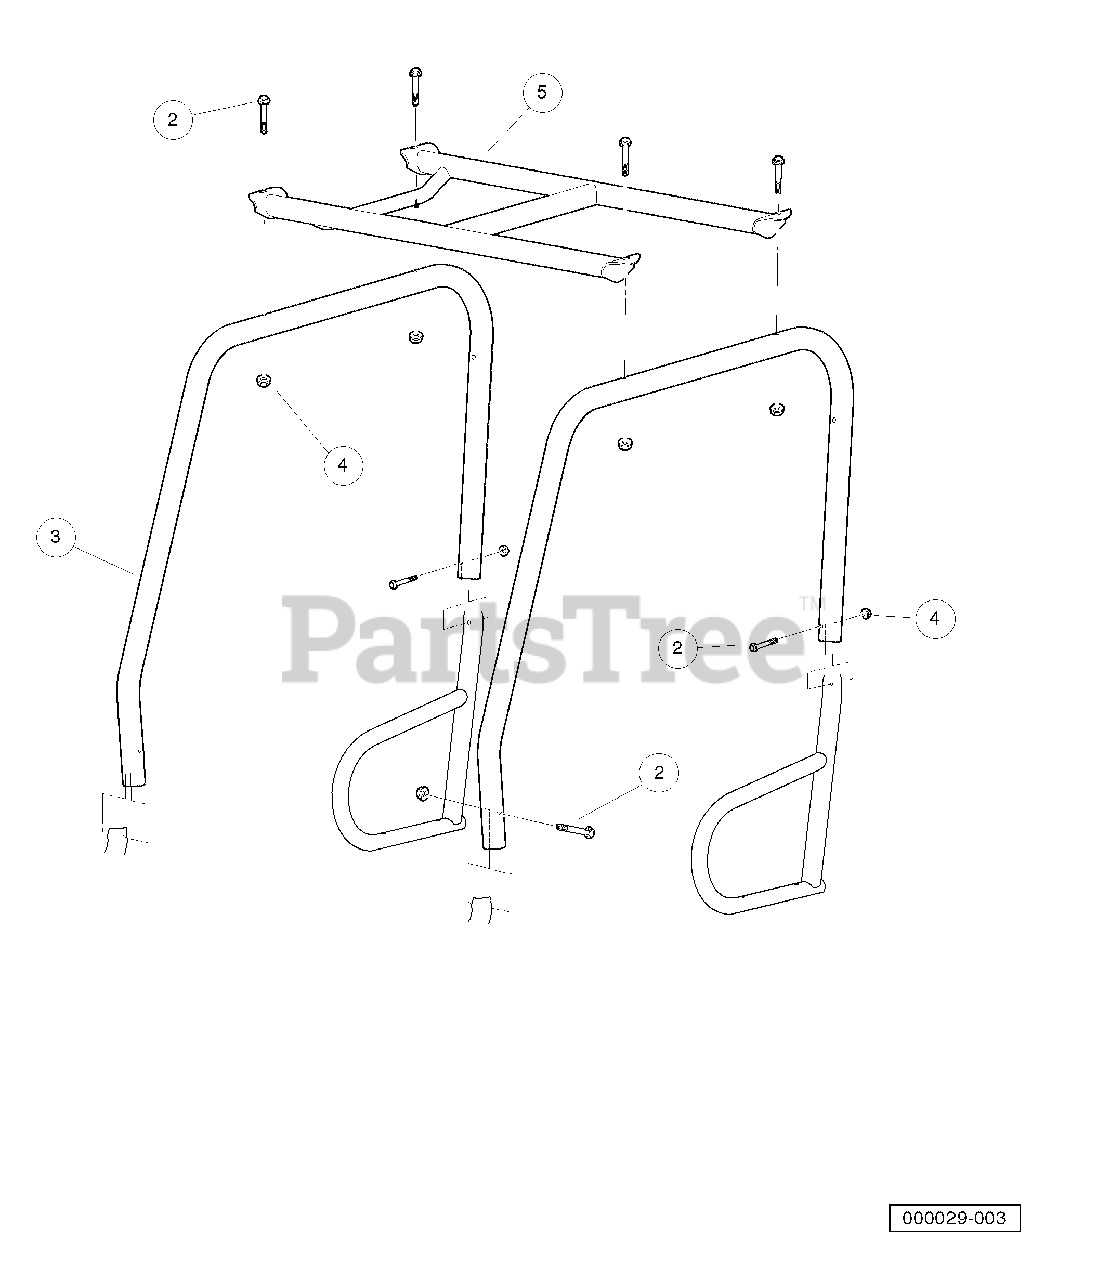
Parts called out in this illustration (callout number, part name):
1	Kit, ROPS, Domestic
2	Bolt, Flanged, M10 X 1.5 X 65
3	Tube, Side Support Short, ROPS
4	Nut, Flanged, M10 x 1.5, Black
5	Asm, Top, ROPS
